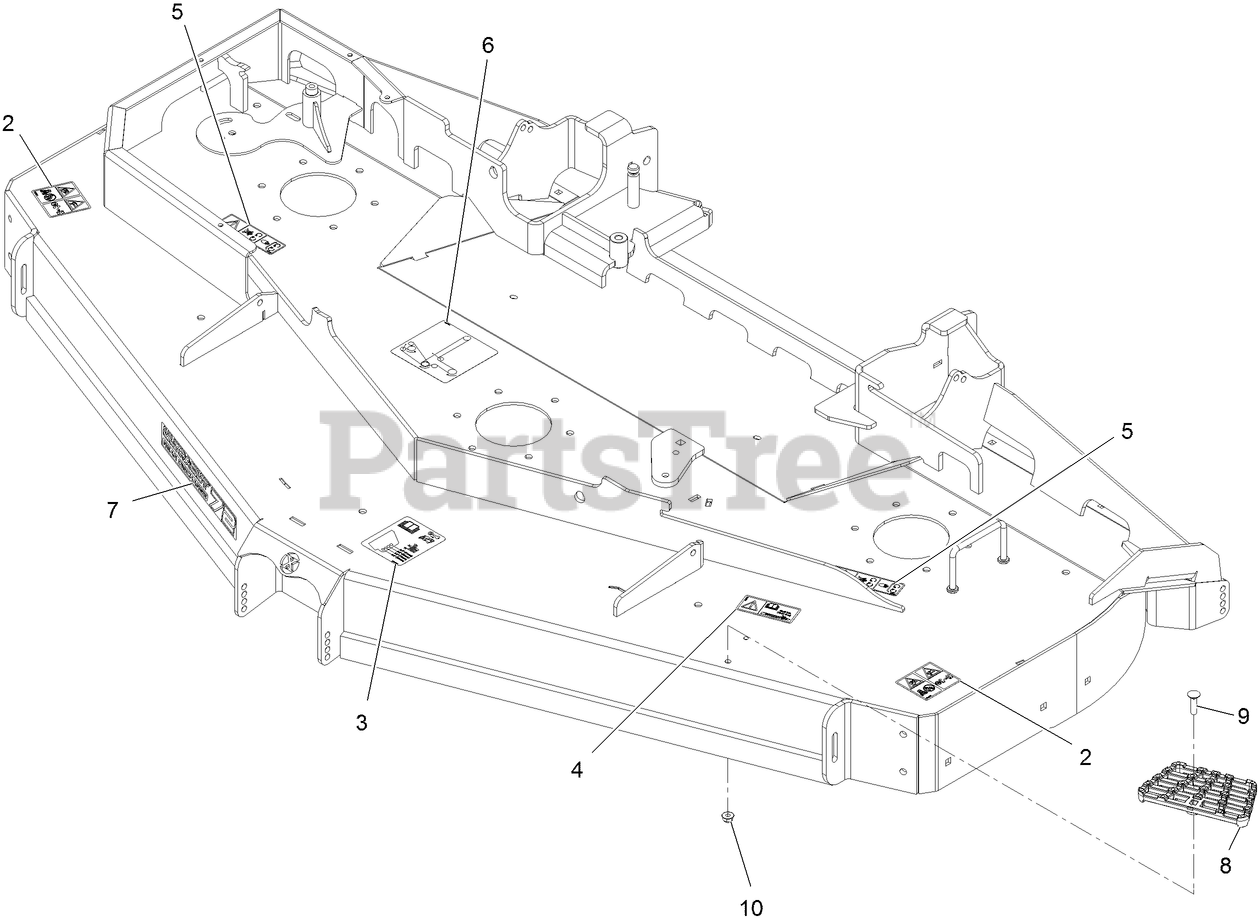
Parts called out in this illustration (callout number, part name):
2	DECAL-DANGER, THROWN OBJECT
3	DECAL-ROLLER, ANTI-SCALP
4	DECAL-TORQUE, BOLT
5	DECAL-COVER, MISSING
6	DECAL-ROUTING, BELT
7	Decal, 72Rd
8	STEP-DECK
9	Bolt-Carriage 5/16-18 X 1 1/4
10	NUT-HF, NI
